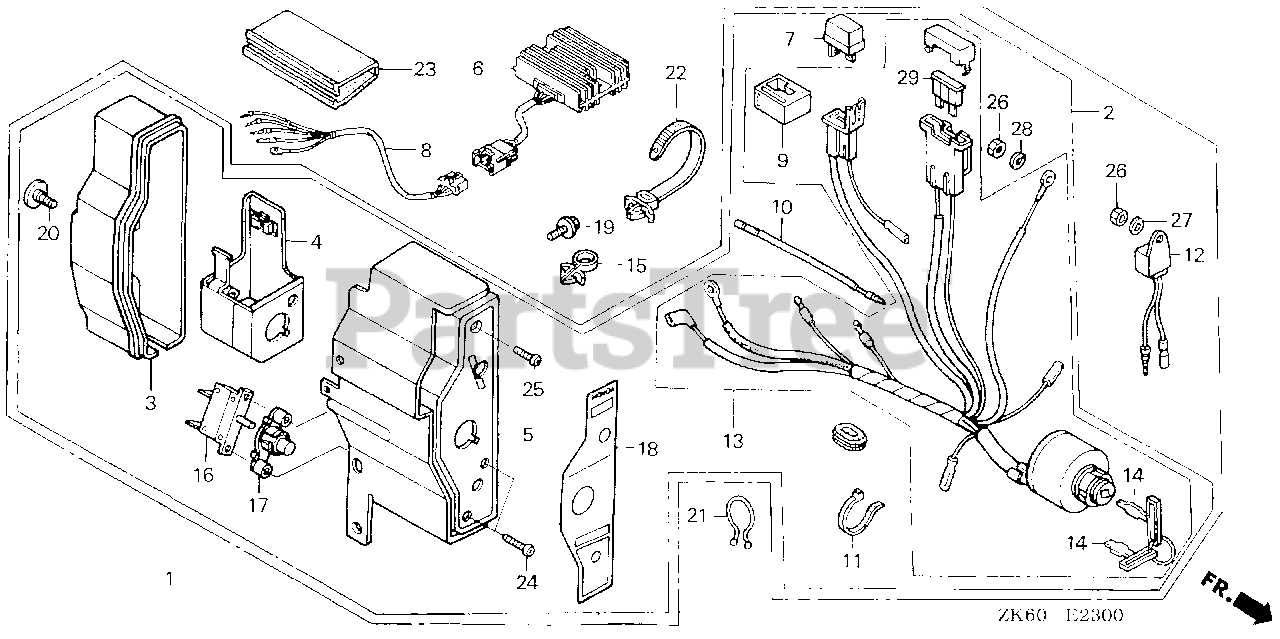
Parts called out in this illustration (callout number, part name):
1	BOX ASSY., CONTROL *NH105* (ALERT) (MAT BLACK)
1	BOX ASSY., CONTROL *R280* (ALERT) (POWER RED)
3	CASE, CONTROL
4	BRACKET, CASE MOUNTING
5	PANEL, CONTROL *NH105* (MAT BLACK)
5	PANEL, CONTROL *R280* (POWER RED)
7	RECTIFIER ASSY., SILICON (SHINDENGEN)
9	SUSPENSION, CONNECTOR
10	SUB-WIRE HARNESS
12	ALERT UNIT, OIL
13	SWITCH ASSY., COMBINATION
14	KEY (HONDALOCK)
15	HOLDER, STOP SWITCH WIRE
16	PROTECTOR, CIRCUIT (1.0A)
17	LENS ASSY., PROTECTOR
18	MARK, CONTROL BOX (EXP)
19	BOLT, FLANGE (6X12) (CT200)
20	SCREW, SPECIAL (6X12)
21	CLIP, PURSE LOCK
22	STRAP, CABLE (118MM) (BLACK)
23	TUBE, FASTENER (30MM)
24	SCREW, PAN (3X12)
25	SCREW, PAN (4X12)
26	NUT, HEX. (4MM) (SOURCE: VINTAGE PARTS INC.)
27	WASHER, PLAIN (4MM)
28	WASHER, SPRING (4MM)
29	FUSE, BLADE (5A)
